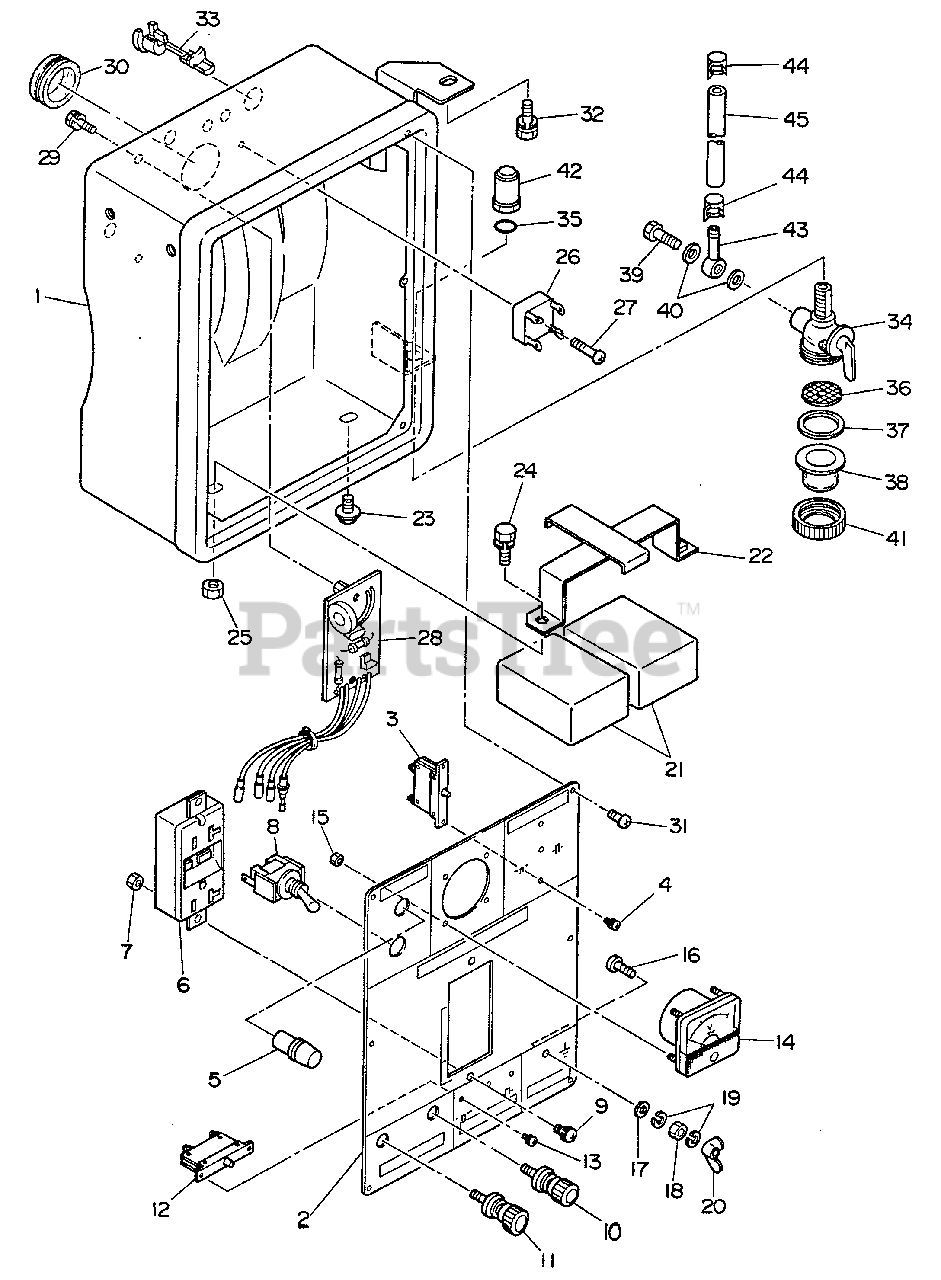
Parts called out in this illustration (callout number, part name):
1	CONTROL BOX ASSY
2	CONTROL PANEL ASSY
3	CIRCUIT BREAKER
4	SCREW
5	LAMP, NEON
6	AC RECEPTACLE - 125V-20A, GFCI
7	NUT
8	SWITCH ASSY
9	SCREW
10	BOLT, TERMINAL - RED
11	BOLT, TERMINAL - BLACK
12	CIRCUIT BREAKER - 10A DC
13	SCREW
14	AC VOLT METER
15	NUT
16	SCREW
17	WASHER
18	NUT
19	WASHER, SPRING
20	WINGNUT
21	CONDENSER
22	CONDENSER BRACKET ASSY
23	BOLT, FLANGE
24	BOLT
25	NUT
26	DIODE STACK ASS'Y
27	SCREW - TAPPING
28	IDLE CONTROL UNIT
29	SCREW
30	GROMMET
31	SCREW - TAPPING
32	BOLT
33	CORD BUSH
34	FILTER, FUEL
35	O-RING
36	FILTER
37	PACKING
38	CUP
39	BOLT, BANJO
40	FIBER PACKING
41	NUT, LOCK
42	CLAMP, HOSE
43	BOLT, BANJO
44	CLAMP, HOSE
45	RUBBER PIPE (4.5 DIA.×11 DIA.×160 MM)
